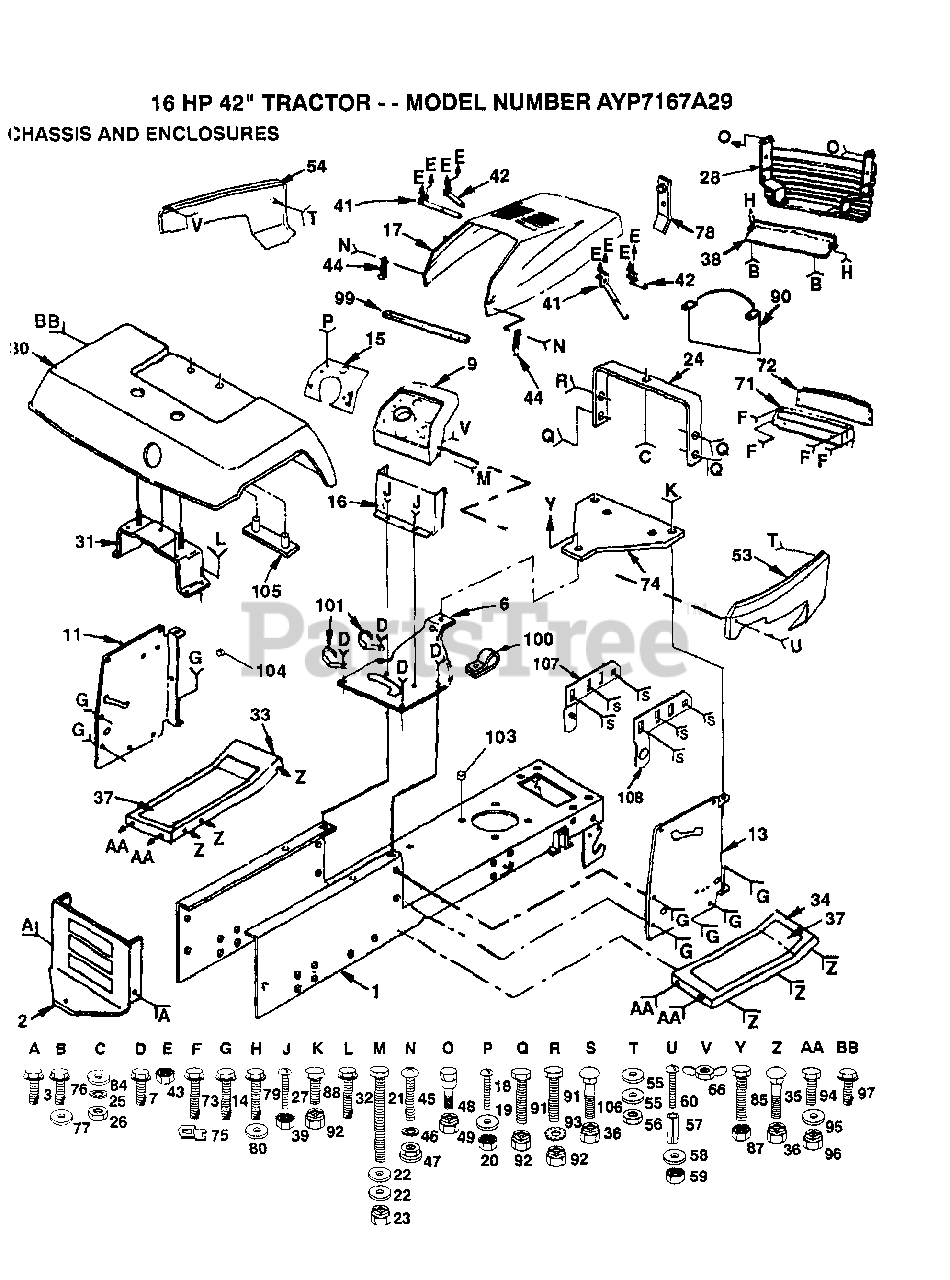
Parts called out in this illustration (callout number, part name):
3	SCREW
7	SCREW LT
11	"PANEL,DASH"
14	SCREW
16	DASH ASSY LT
18	SCREW
19	WASHER
22	WASHER
24	SUPPORT ASS'Y
25	LOCKWASHER
27	SCREW
30	FENDER
32	SCREW
35	BOLT
37	FOOTREST PAD
43	NUT
44	HOOD LATCH T
45	SCREW
46	LOCKWASHER
47	WELDNUT
55	WASHER PM
57	SPACER LT
58	WASHER
60	SCREW
72	LENS LT
75	"""J"" FASTENER LT"
76	SCREW
77	WASHER
79	SCREW HEX CRT
80	WASHER
84	WASHER PM
85	BOLT
90	BAFFLE
93	LOCKWASHER
95	WASHER
97	SCREW LT
99	FOAM-STRIP LT
100	CLIP T
101	CLIP T
103	SNAP BUSHING T
106	BOLT
107	CROSS BRACE
108	PIVOT BRKT RH
